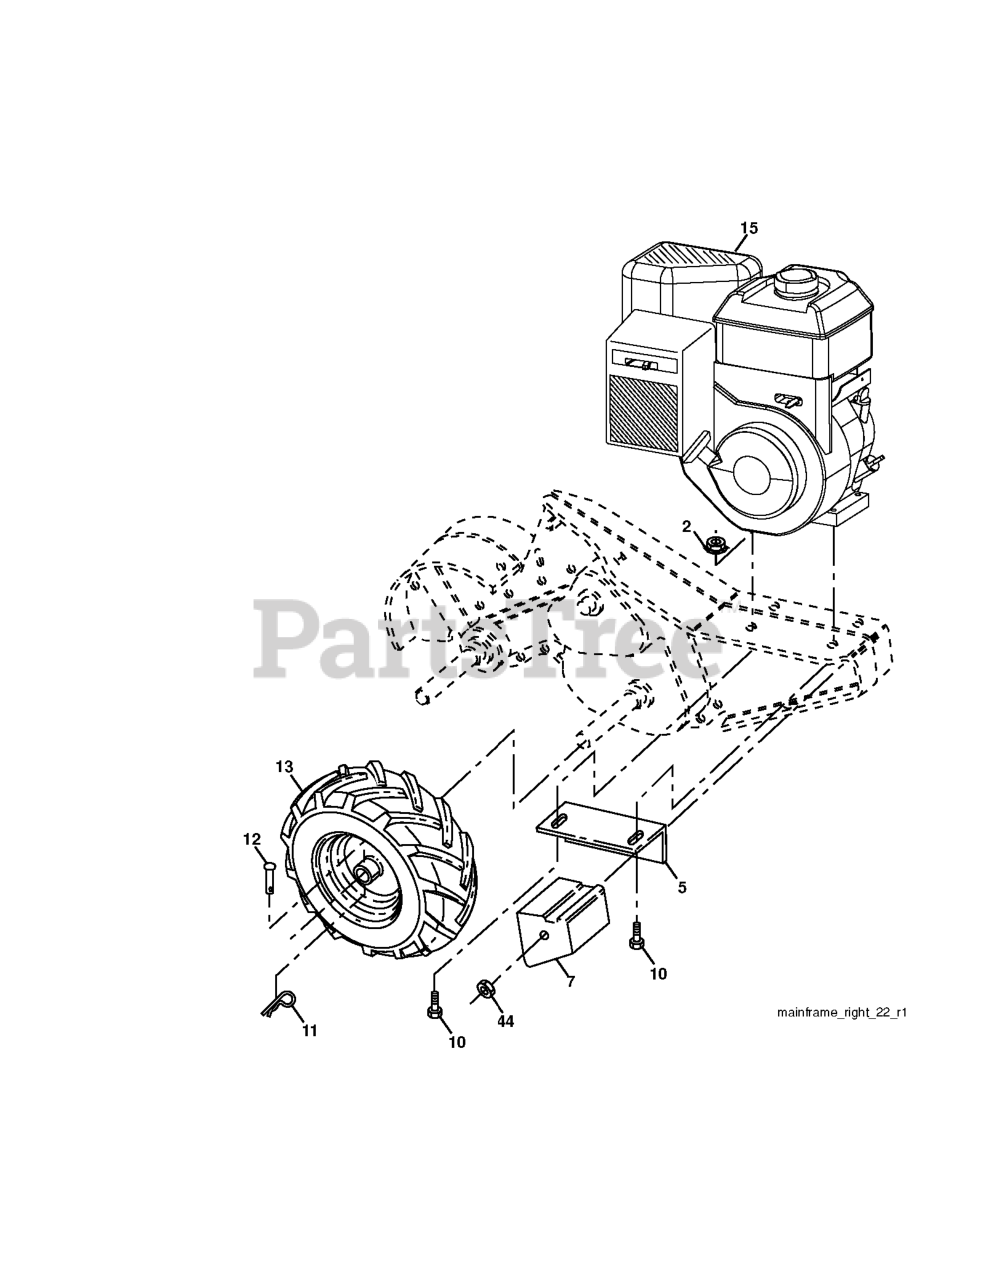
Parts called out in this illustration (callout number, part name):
2	LOCKNUT-FLANGE 5/16-18
5	DNO BRACKET RH CRT
7	COUNTERWEIGHT, RH
10	BOLT
11	RETAINER M
12	RIVET,DRILLED
13	TIRE.13X5-6.CHEVRON.TILLER
